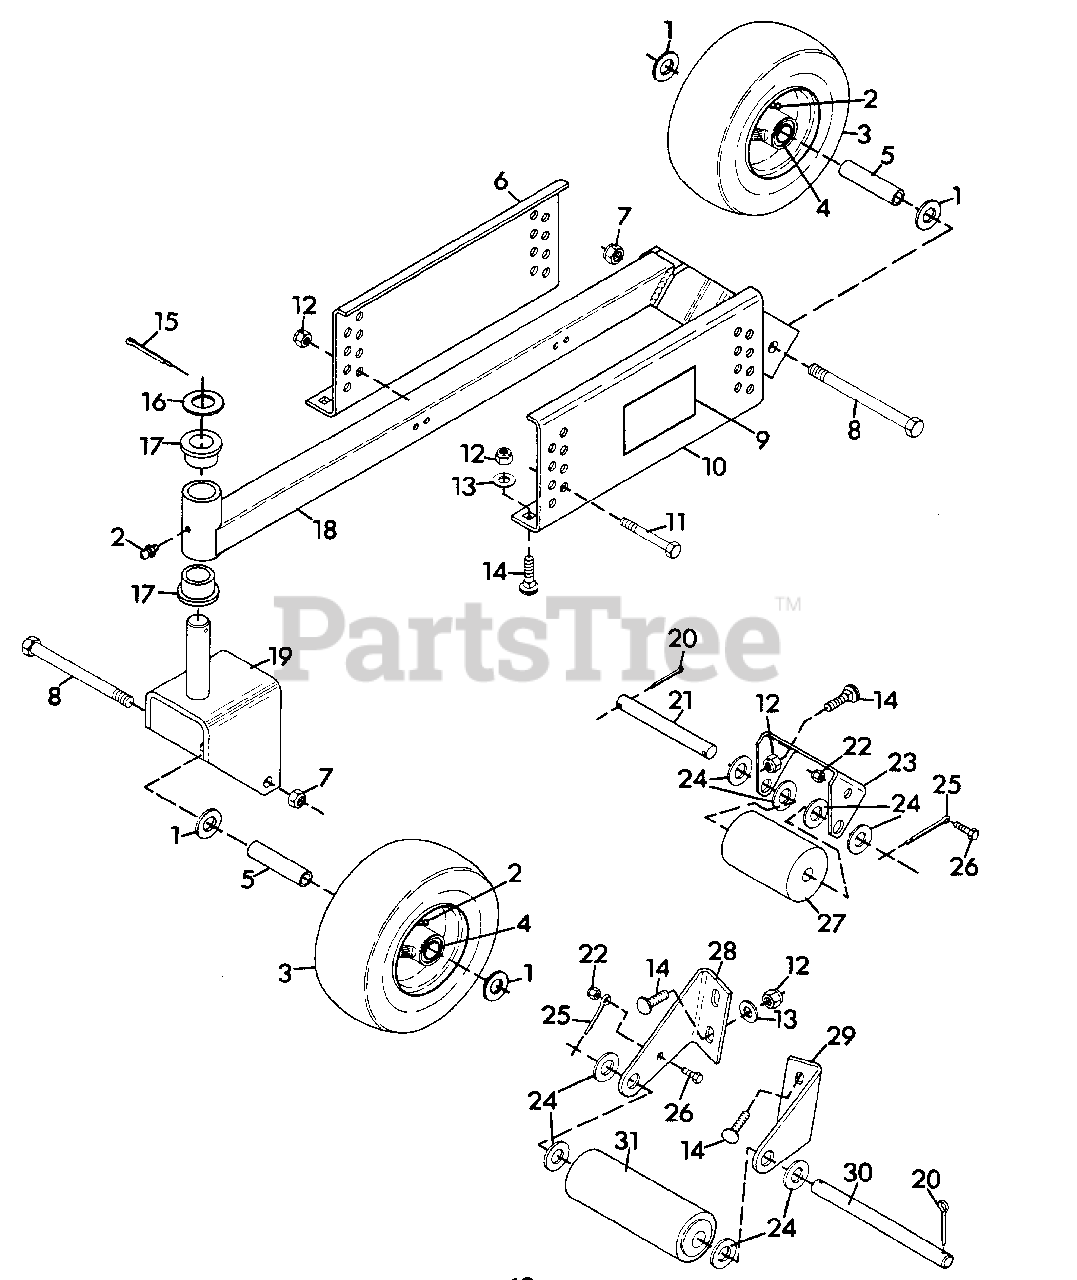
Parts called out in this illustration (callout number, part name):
1	Washer, Flat .531x1.250x.100
2	Fitting, Lube 1/4-28
3	Wheel, Gauge
4	Bearing, Gauge Wheel
5	Bushing, Wheel
6	Hanger, L.H.
7	Nut, Lock 1/2-13
8	Bolt, Hex 1/2-13x5.00
9	Decal, Danger Foot
10	Hanger, R.H.
11	Bolt, Hex 3/8-16x2.50
12	Nut, Lock 3/8-16
13	Washer, Flat .406x.812x.065
14	Bolt, 3/8-16x1.00 Rd Hd Sq Nk
15	Pin, Cotter .187x1.625
16	Race, Bearing Thrust
17	Bushing, Pivot
18	Weldment, Caster Wheel Support
19	Weldment, Caster Fork
20	Pin, Cotter .25x1.00
21	Rod
22	Nut, Hex 1/4-20
23	Bracket, Roller
24	Washer, Flat .656x1.312x.095
25	Pin, Cotter .250x2.00
26	Bolt, Hex 1/4-20x.75
27	Roller, Gauge
28	Bracket, Roller L.H.
29	Bracket, Roller R.H.
30	Shaft, Center Roller
31	Roller, Gauge
